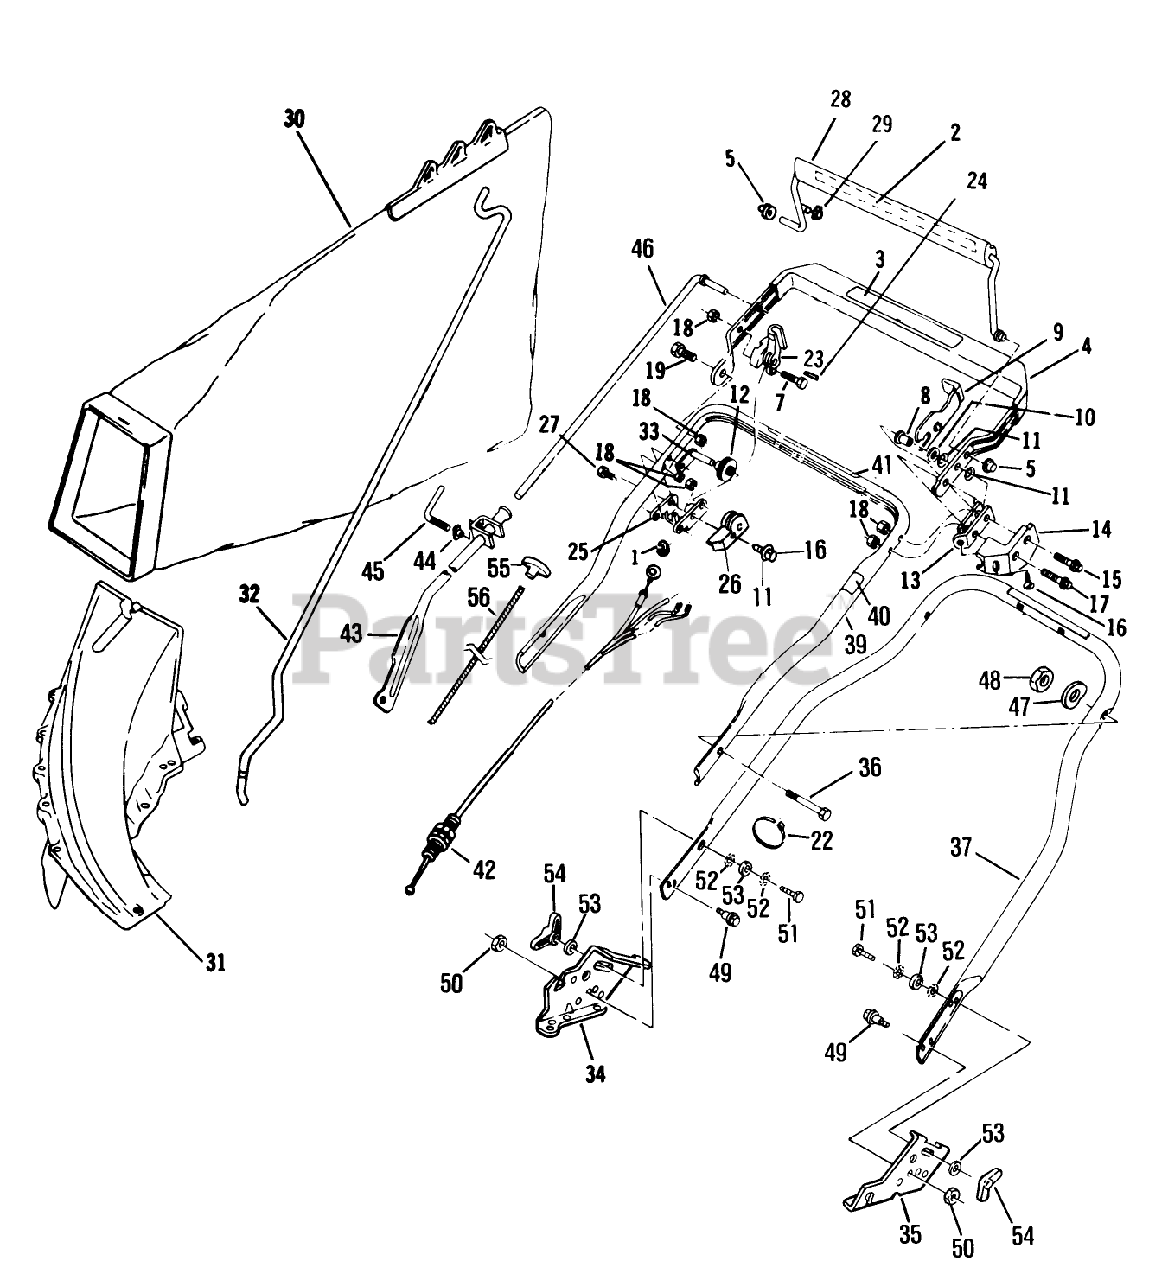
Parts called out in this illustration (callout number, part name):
1	RET. RING
8	SPACER
10	WASHER M
13	DOWN STOP
14	LOCKOUT GUARD
15	BOLT SHOU
16	SCREW F
17	SCREW
18	LOCKNUT E
19	BOLT
23	CAM (12)
29	NUT ACORN
30	89802 LB WHOLE GOODS
32	ROD GRASSBAG
42	CONTROL CABLE
46	CONTROL ROD
48	NUT-LOCK F
49	BOLT
50	NUT-JAM, LOCKING
52	LOCK WASHER LARSON
53	WASHER
54	NUT-WING
55	HANDLE START UM&D
